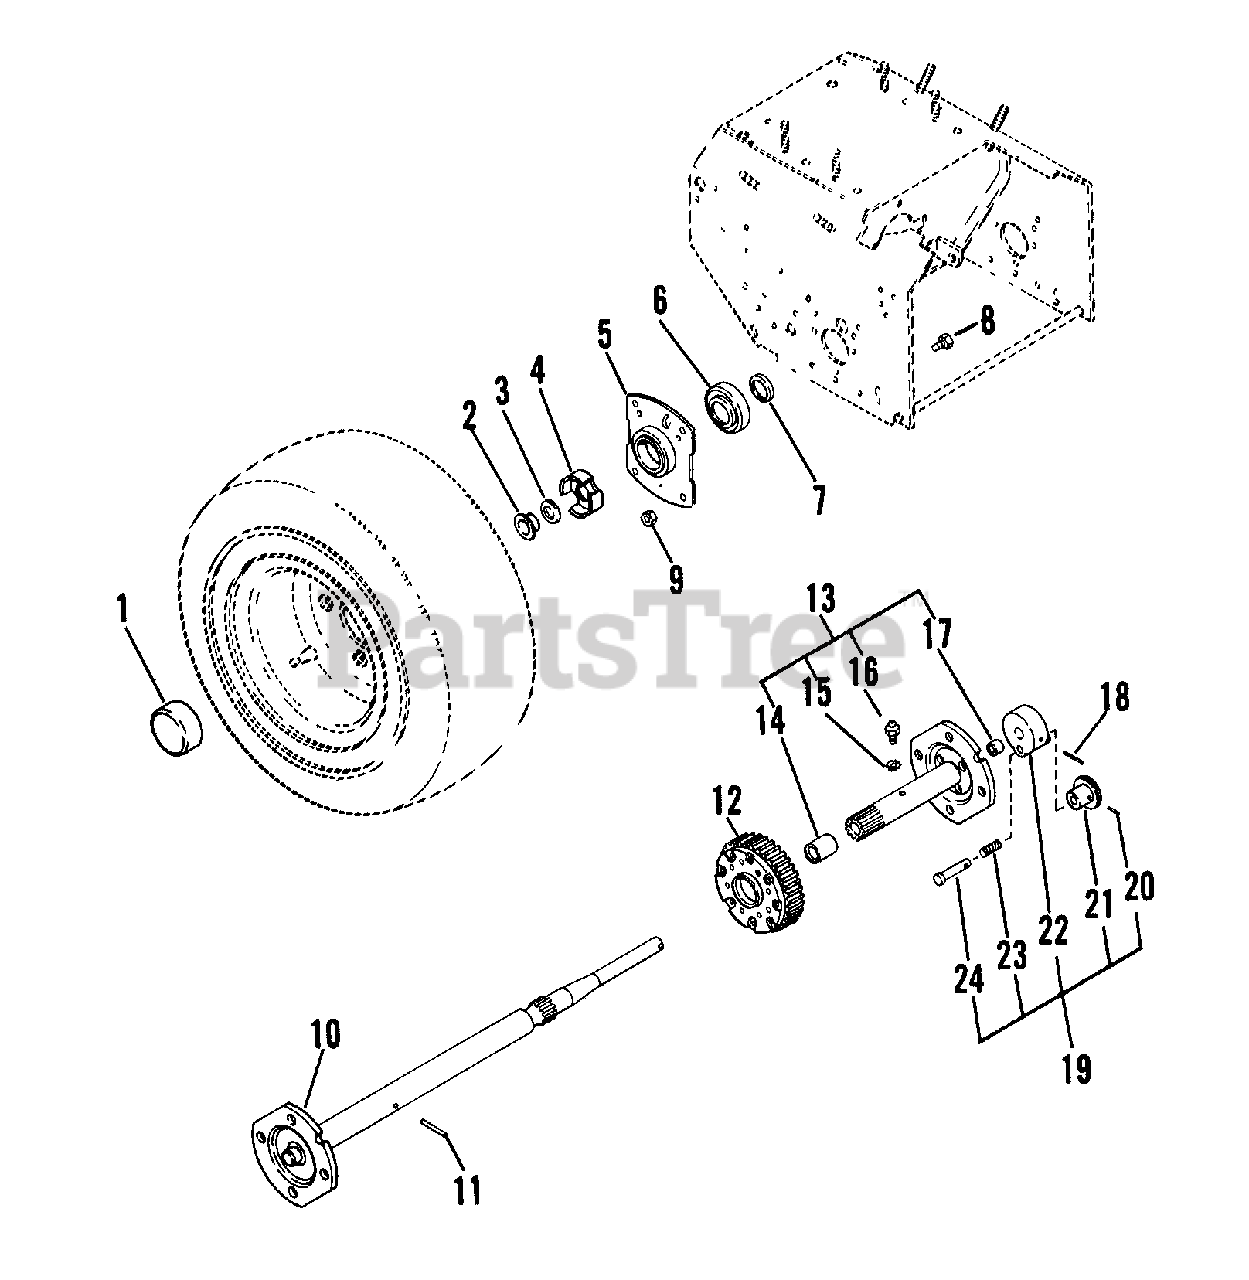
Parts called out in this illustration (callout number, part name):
1	HUB CAP
2	PUSHNUT
3	WSHR-FL-STL .755X2.000X.125
4	SPINDLE CUP
5	BEARING RETAINER
5	SUPPORT, BEARING
6	BRG-BALL 1.13X2.18X.63
6	BSHG-FLG.875X1X.625X1.250 BR
7	WSHR-FL-STL 1.140X1.718X.134
7	WSHR-FL-STL .880X1.380X.062
8	SCR-SLTR-SERNK .25-20X.62 PL
9	NUT-LK-FLG .250-20 PL
10	R H AXLE
10	R H AXLE SHAFT
11	PIN-ROLL .188X1.50
11	PIN-ROLL .188X1.25
12	DIFFERENTIAL ASSEMBLY
13	L.H.AXLE ASSEMBLY
13	L.H. AXLE ASSEMBLY
14	BSHG-SLV .500X.687X.500 SI
14	BSHG-SLV .562X.625X.625 BRZ
15	WSHR-LK .250X.047 LT PL
16	SPIN DRIVE ZERK FITTING
17	BSHG-SLV .562X.625X.625 BRZ
18	PIN-GRV .250X1.75 TP C
19	LOCKOUT HUB ASSEMBLY
20	PIN-ROLL .093X1.00
22	LOCKOUT HUB
23	SG-COMP .028X.34X1.062 WLD75
